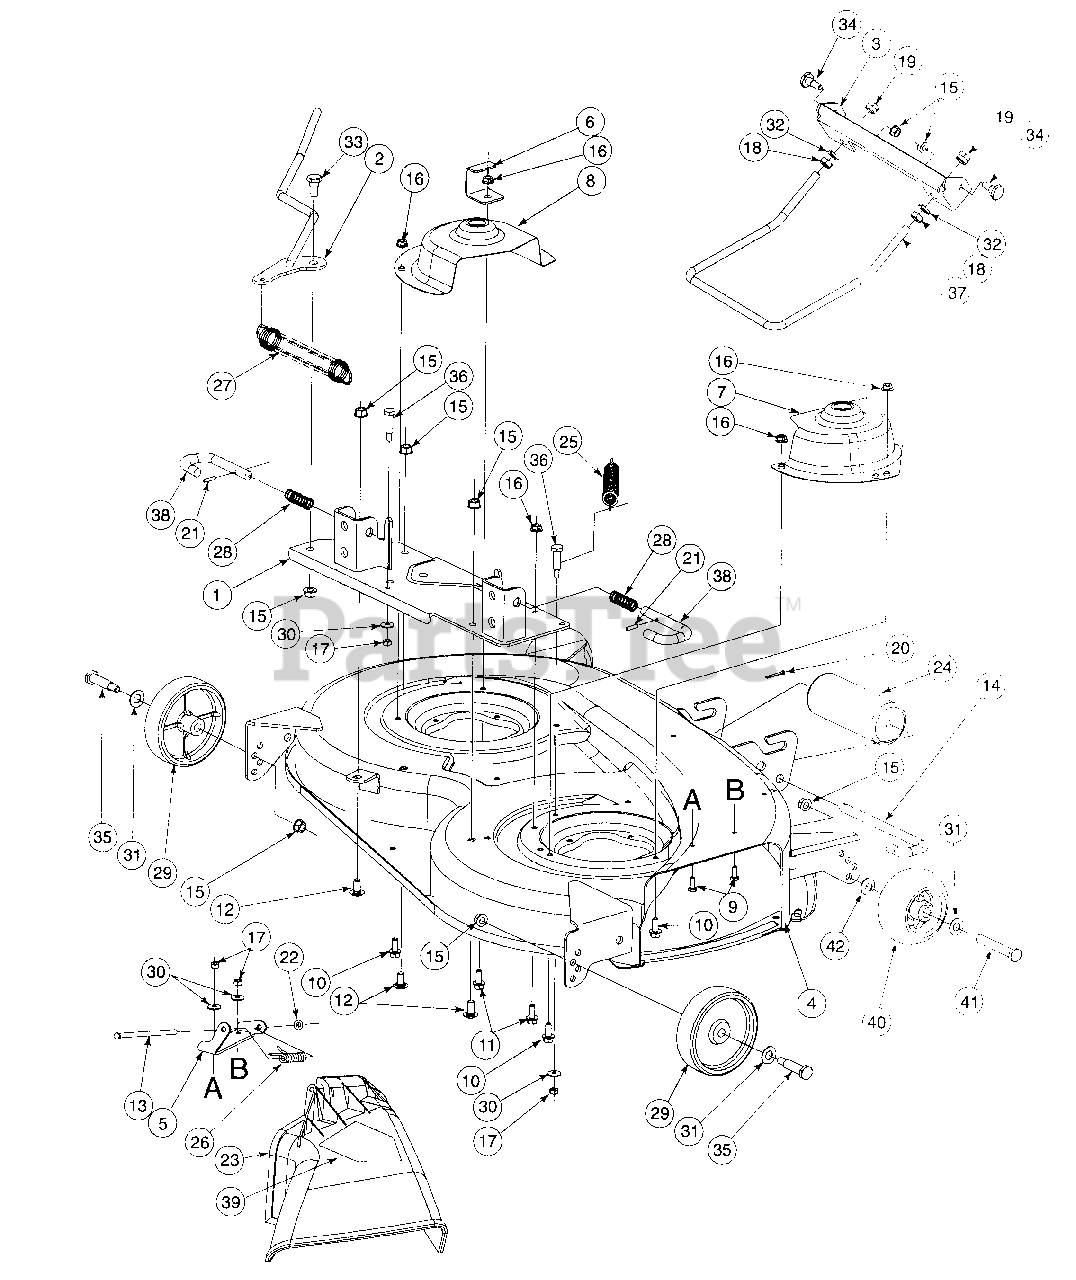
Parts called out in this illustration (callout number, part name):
1	Plate Assembly, Mounting
3	Bracket, Front Lift
4	Deck, 38" w/out Front Wheel bracket
4	Deck, 38" w/Front Wheel bracket
4	Graphic, Danger Top/RH Deck
4	Graphic, Tension Lever
4	Graphic, Safety Top/LH Deck
4	Graphic, Assembly Chute
5	Bracket, Hinge Mounting
6	Bracket, Handle Stop
7	Shield, RH Pulley
8	Shield, LH Pulley
9	Screw, Hex Cap, 1/4-20 x .62 GR5
10	Screw, Hx Wsh Hd Tapp, 5/16-18 x.75
11	Screw, Hex Cap, 5/16-18 x .75 GR5
12	Bolt, Carriage, 3/8-16 x .75
13	Pin, Hinge, .25 Dia x 6.75 Lg
14	Pin, Roller, 1/2 Dia x 7.31 Lg
15	Nut, Hex Flange Lock, 3/8-16
16	Nut, Hex Flange Lock, 5/16-18 GR5
17	Nut, Hex, 1/4-20
18	Nut, Hex Jam, 1/2-13 GR5
19	Nut, Hex Insert Lock, 1/2-13
20	Pin, Cotter, 3/32 x 1.25
21	Pin, Spirol Spring, 3/16 x .75
22	Cap, Speed Nut
23	Deflector Assy,
25	Spring, Extension, .88 OD x 6.12
26	Spring, Torsion
27	Spring, Extension, 1.25 OD x 8.15
28	Spring, Compression
29	Wheel, Deck, 5 in. Dia
30	Washer, Bell, .265 x .75 x .062
31	Washer, Flat, .510 x 1.0 x .060
32	Washer, Lock, 1/2
33	Bolt, Shoulder, .498 Dia x .340 Lg
34	Bolt, Shoulder, .50 Dia x .434 Lg
35	Bolt, Shoulder, .498 Dia x 1.64 Lg
36	Bolt, Shoulder, .375 Dia x 1.16 Lg
37	Rod, Front Lift
38	Pin, Mower Support
39	Graphic, Danger
40	Wheel, Deck w/Fitting
40	Lube Fitting
41	Bolt, Shoulder, 1/2 x 2.5
42	Washer, Bell, .401 x .870 x .063
